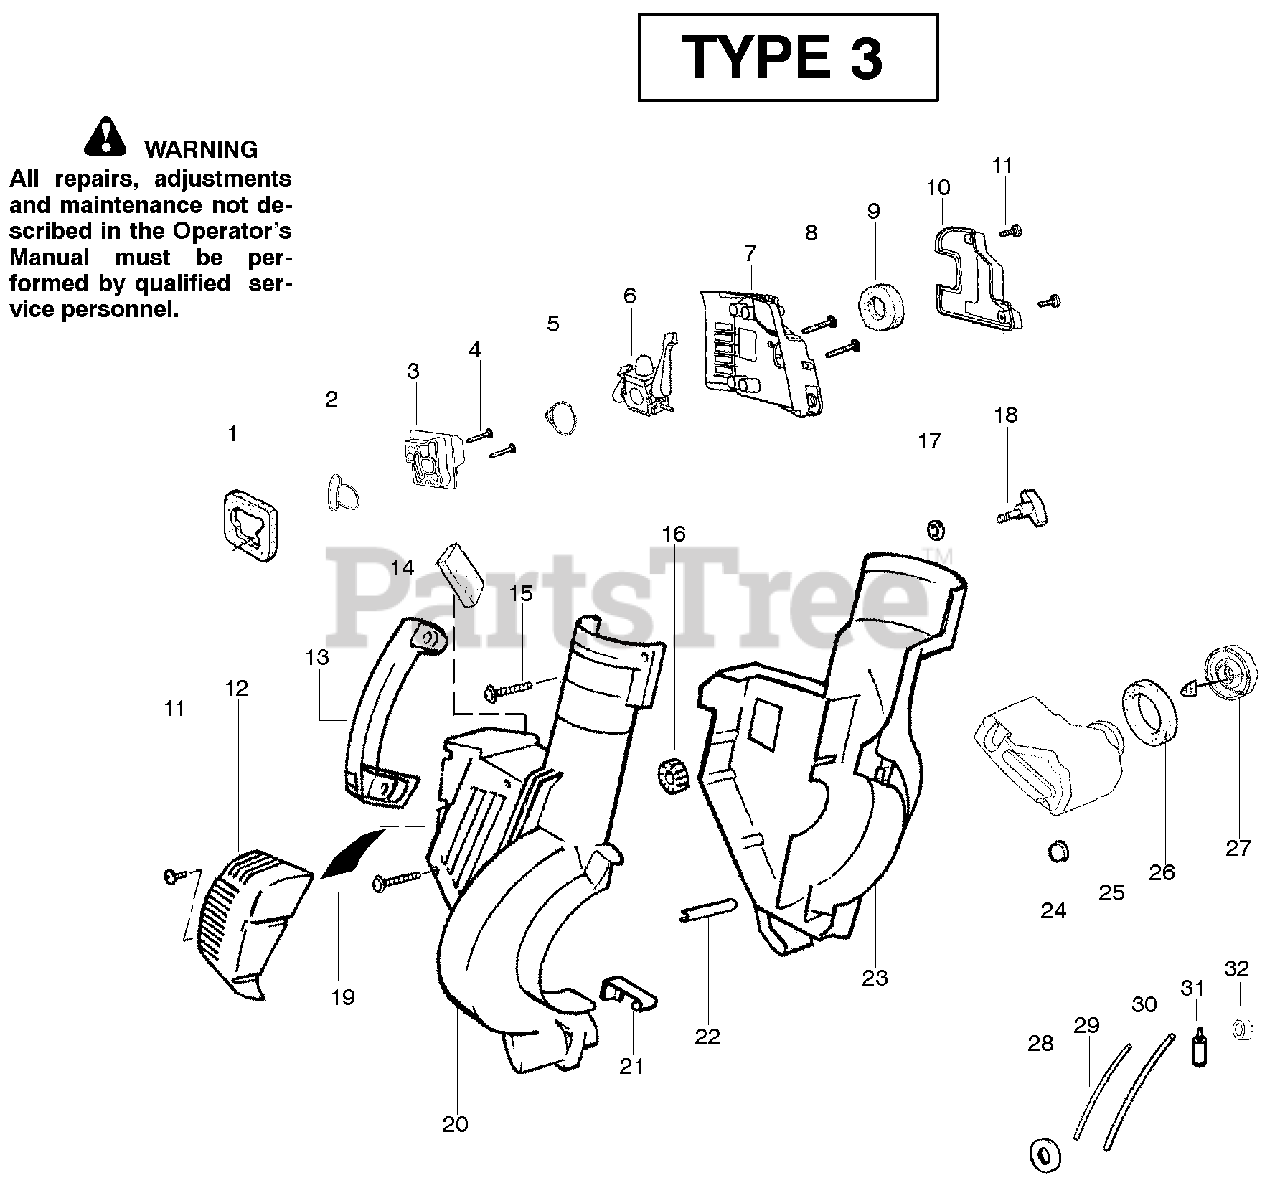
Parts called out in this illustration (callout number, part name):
1	Air Dam (kit)
2	Gasket-Adapter (kit)
3	Carburetor Adaptor
5	Gasket-Carburetor (kit)
6	Kit-Carb Ass'y. (C1Q-W11)
6	Kit-Carb Ass'y. (C1Q-W11C)
8	Screw-Carb.
9	Filter-Air
10	Cover-Air Filter
12	Guard-Muffler
14	Foam - 71.12mm (kit)
16	Isolator
18	Knob-Tube Clamp
19	Reflector-Heat (kit)
20	Assy-Housing-Right
21	Spring-Cover Latch
22	Guide-Starter Rope
23	Housing-Left
24	Isolator-Crankcase
25	Assy-Fuel Tank
26	Gasket-Fuel Tank
27	Fuel Cap w/Retainer
28	Grommet-Shroud
29	Kit-Line Carb/Purge
30	Kit-Line Tank/Purge
31	Assy-Fuel Pick-up
32	Grommet-Fuel line (kit)
